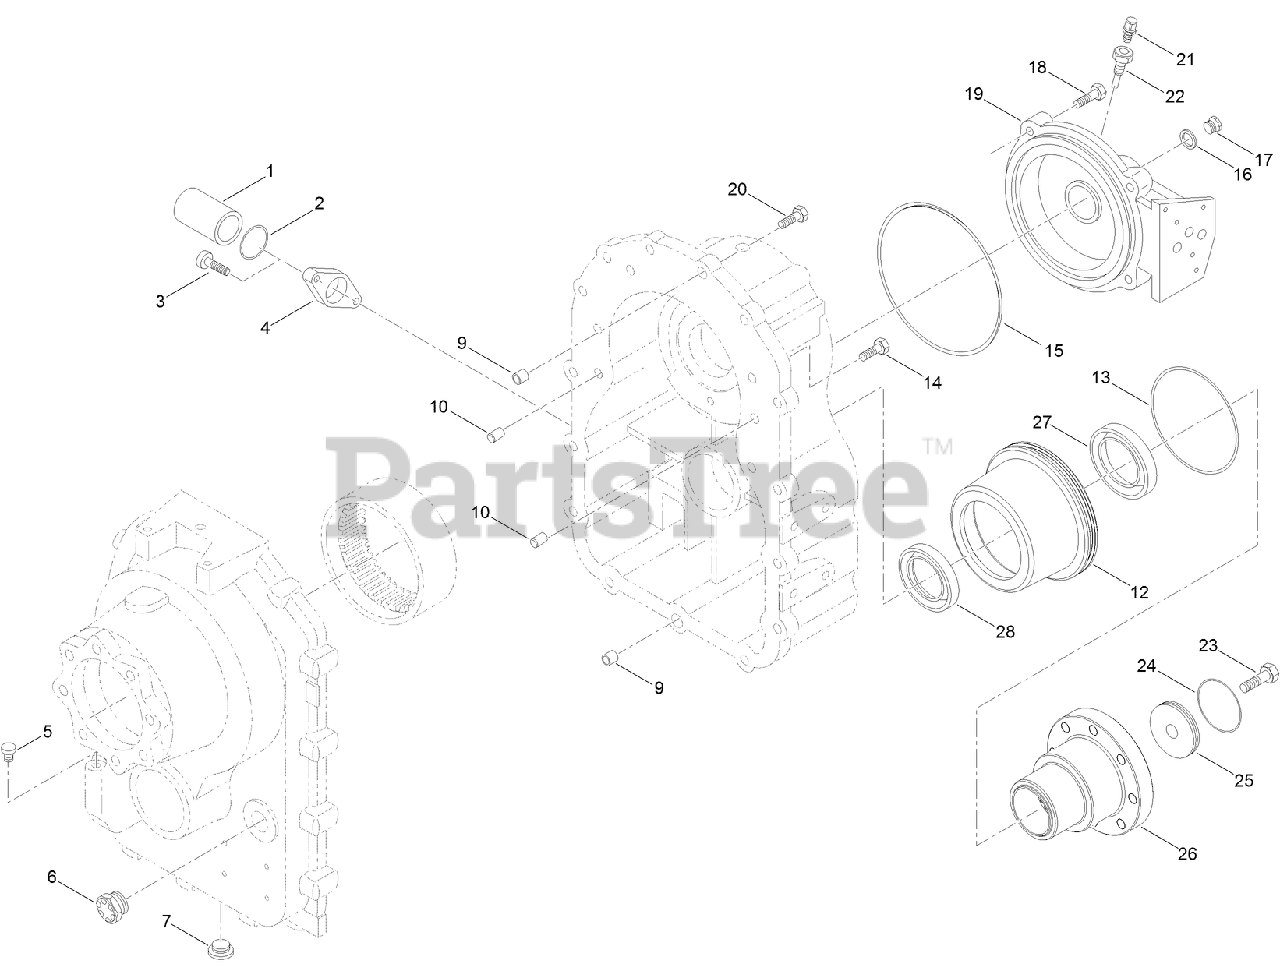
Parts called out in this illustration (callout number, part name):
2	FILTER-SCREEN
3	SCREW-CAP
6	PLUG-LEVEL, OIL
7	PLUG-DRAIN
9	BUSHING
10	PIN-DOWEL
12	SHAFT-OUTPUT
13	O-RING
14	BOLT-HEX FLG
18	SCREW-CAP
19	HOUSING-COVER, PARK BRAKE
21	BREATHER
22	EXTENSION-BREATHER
27	SEAL-LIP
28	SEAL-LIP
